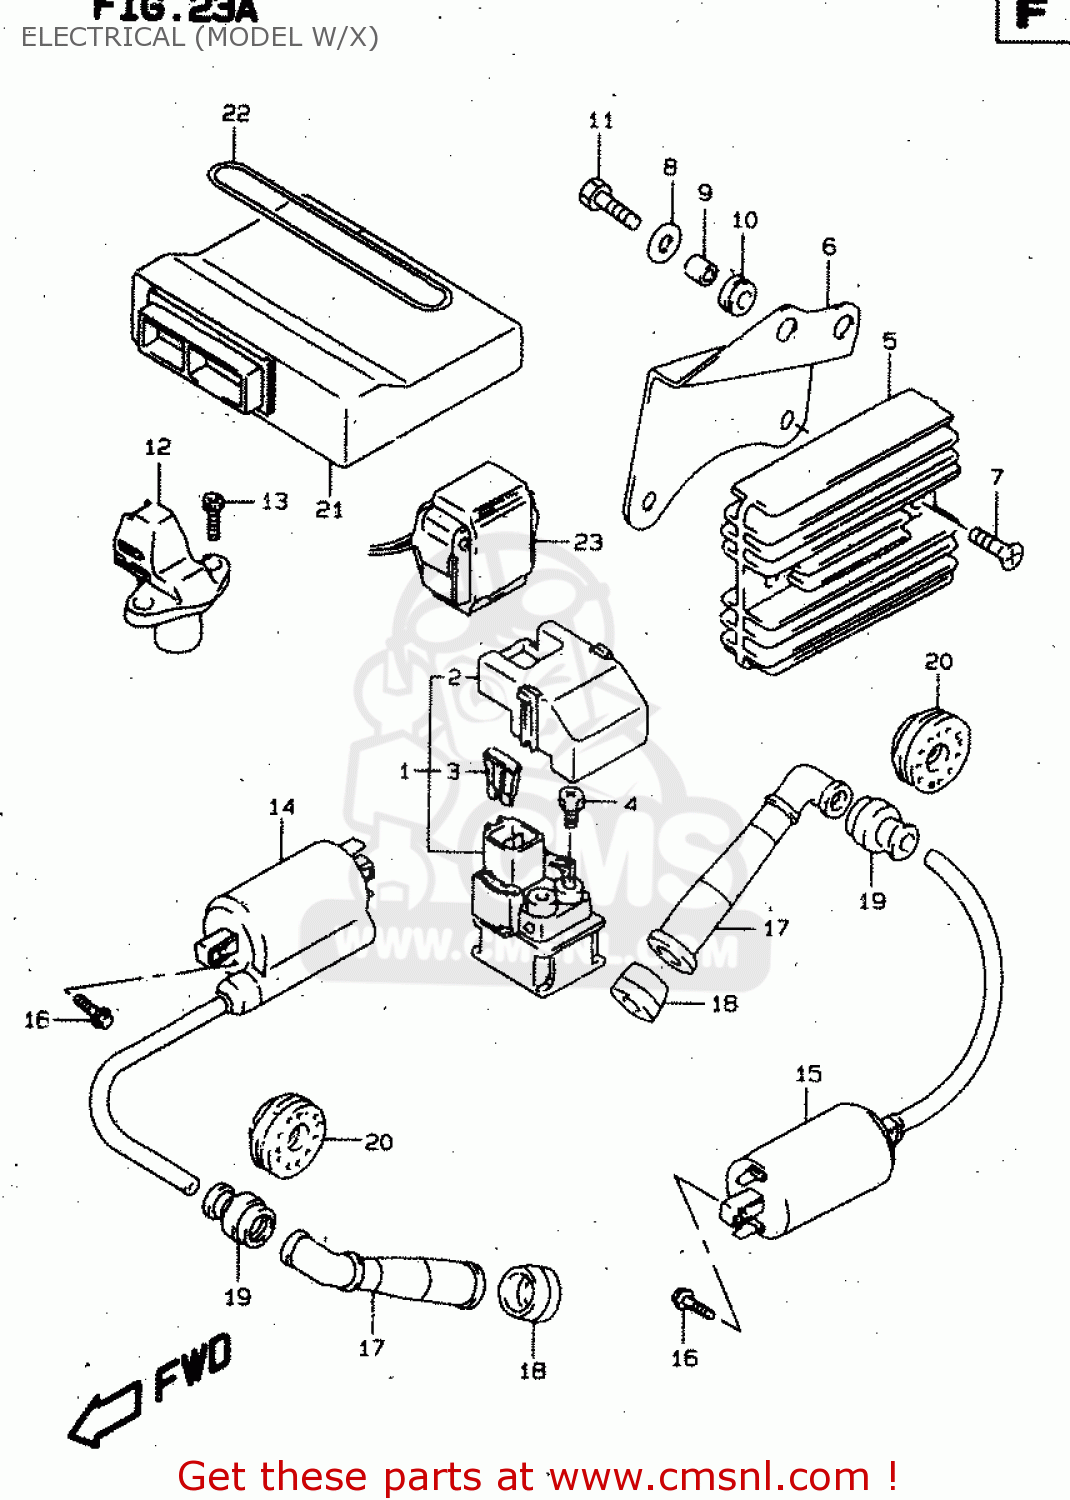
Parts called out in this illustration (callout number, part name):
1	RELAY ASSY,STARTING MOTOR
2	COVER,RELAY ASSEMBLY
3	FUSE(30A)
4	SCREW(6X8)
5	RECTIFIER ASSY
6	BRACKET,RECT FTG
7	SCREW (6X20)
8	WASHER(6.5X18X1.6)
9	SPACER(6.5X9X6.7)
10	CUSHION
11	BOLT
12	SENSOR ASSY,CAM POSITION
13	SCREW 6X16
14	COIL ASSY,IGNITION
15	COIL ASSY,IGNITION
16	SCREW, PRESSURE SENSOR
17	CAP,SPARK PLUG
18	SEAL,SPARK PLUG CAP
19	SEAL,HIGH TENSION CORD
20	COVER,SPARK PLUG CAP
21	CONTROL UNIT,EPI
22	BAND,BATTERY
23	SENSOR ASSY,FUEL CUT
